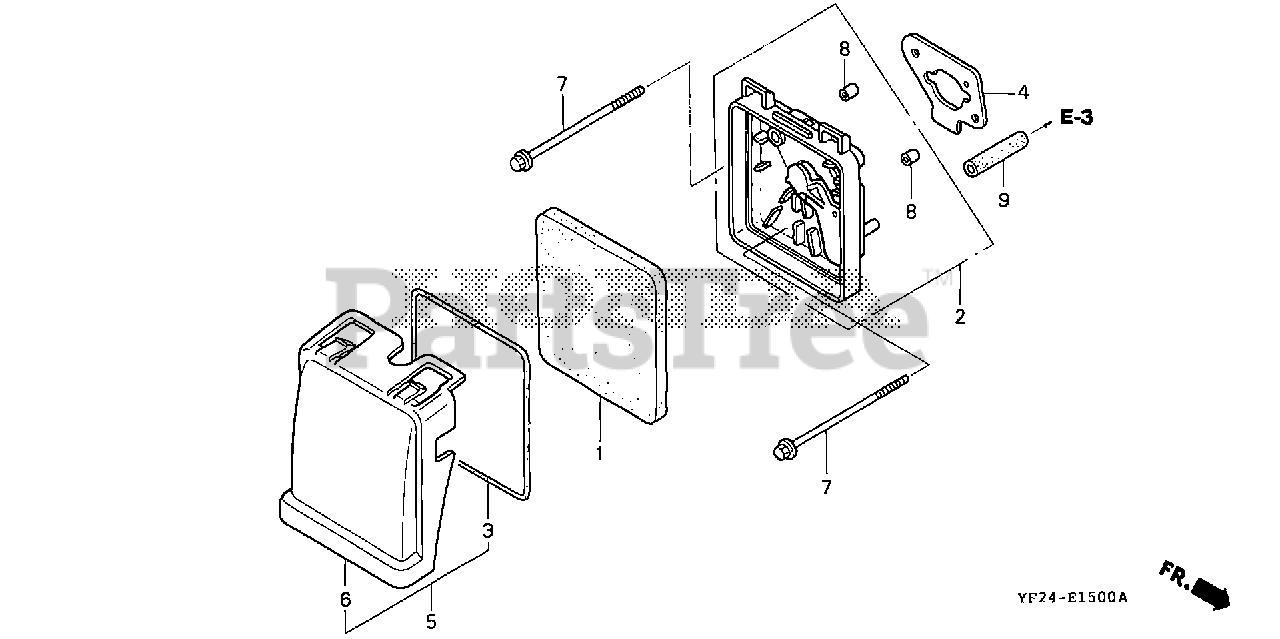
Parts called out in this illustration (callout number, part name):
1	ELEMENT, AIR CLEANER
2	HOUSING, AIR CLEANER
3	SEAL, AIR CLEANER
4	GASKET, AIR CLEANER
5	COVER, AIR CLEANER
6	COVER, AIR CLEANER
7	BOLT, FLANGE (5X75)
8	COLLAR, AIR CLEANER
9	BULK HOSE, VACUUM (7X3000) (7X75)
